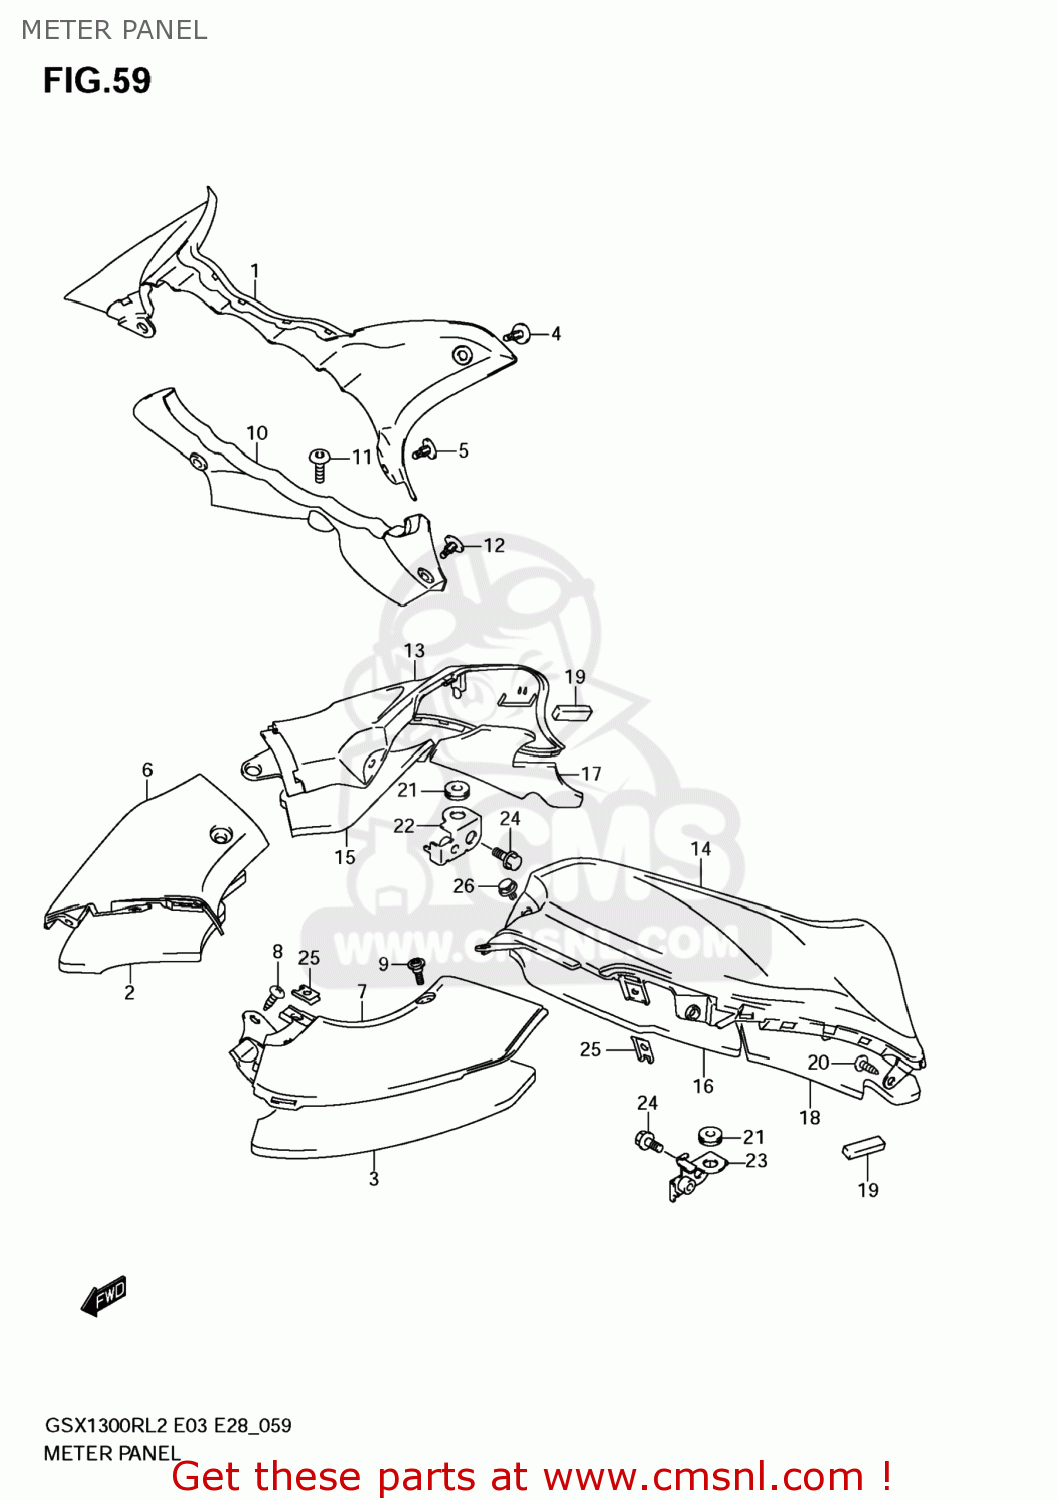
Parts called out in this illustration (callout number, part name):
1	PANEL,METER UPR
2	CUSHION,PANEL UPR,R
3	CUSHION,PANEL UPR,L
4	CLIP(BLACK)
5	CLIP
6	PANEL,UPR,R
7	PANEL,UPR,L
8	SCREW
9	SCREW(5X16)
10	PANEL,METER RR
11	SCREW(5X13)
12	CLIP
13	PANEL,SIDE,R
14	PANEL,SIDE,L
15	CUSHION,SIDE PANEL FR,R
16	CUSHION,SIDE PANEL FR,L
17	CUSHION,SIDE PANEL RR,R
18	CUSHION,SIDE PANEL RR,L
19	CUSHION
20	SCREW(5X16)
21	CUSHION
22	BRACKET,PANEL,R
23	BRACKET,PANEL,L
24	BOLT
25	NUT,COWL
26	CLIP
